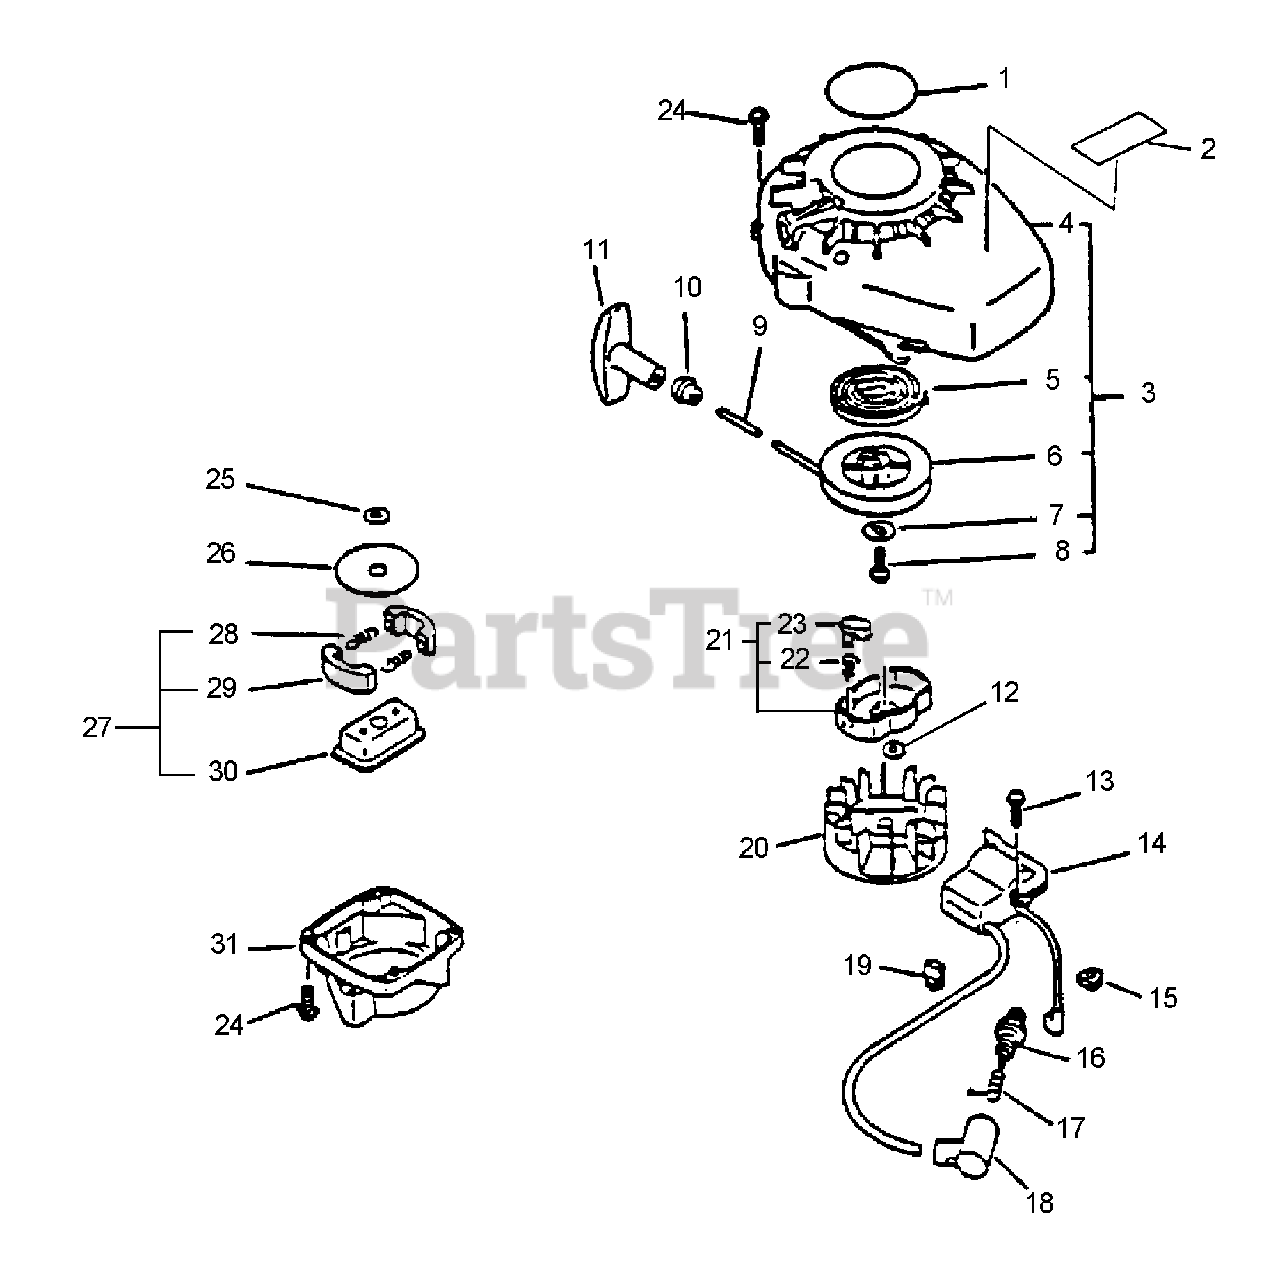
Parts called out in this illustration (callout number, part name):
1	LABEL, HC-1500
2	LABEL - CAUTION
2	LABEL, CAUTION
3	STARTER ASSY
4	COVER, FAN
5	SPRING, RECOIL
6	REEL, ROPE
7	WASHER
9	ROPE, STARTER
10	GUIDE, ROPE
11	GRIP, STARTER
12	WASHER, SPRING 8
13	SCREW 4×22
14	COIL, IGNITION
16	SPARK PLUG - BPM6A
16	SPARK PLUG - RCJ-8Y
17	TERMINAL, SPARK PLUG
18	CAP, SPARK PLUG
20	FLYWHEEL
21	PAWL ASSY, STARTER
22	SPRING, RETURN
23	PAWL, STARTER - BLACK
24	BOLT 4×16
25	WASHER, CLUTCH
26	PLATE, CLUTCH
27	CLUTCH ASSY
28	SPRING, CLUTCH
29	SHOE, CLUTCH
30	BOSS, CLUTCH
31	HOUSING, CLUTCH
